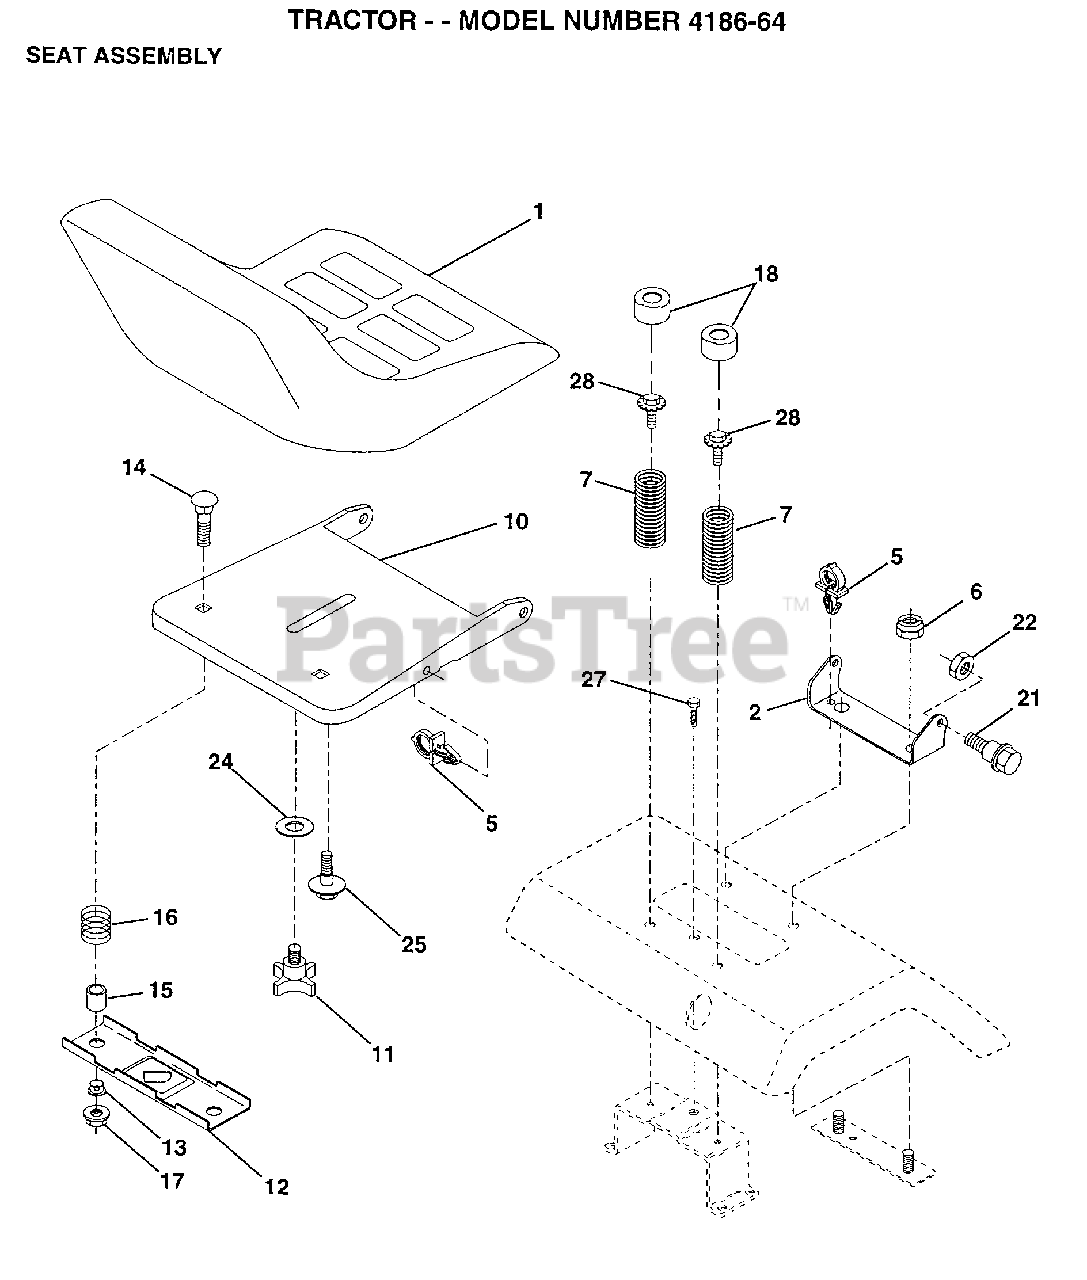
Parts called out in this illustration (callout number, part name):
2	BRACKET PVT SEAT
5	CLIP.PUSH-IN.HING
6	NUT
7	SPRING COMPRESSIO
11	"KNOB 1/2"" YT"
12	BRKT SWITCH
13	BUSHING
15	SPACER SPLIT
16	SPRING COMPRESSED
18	CAP SPRING
21	"BOLT,SHOULDER"
24	WASHER
25	"BOLT,SHOULDER"
27	SCREW LT
28	BOLT.5/16-18.UNC
